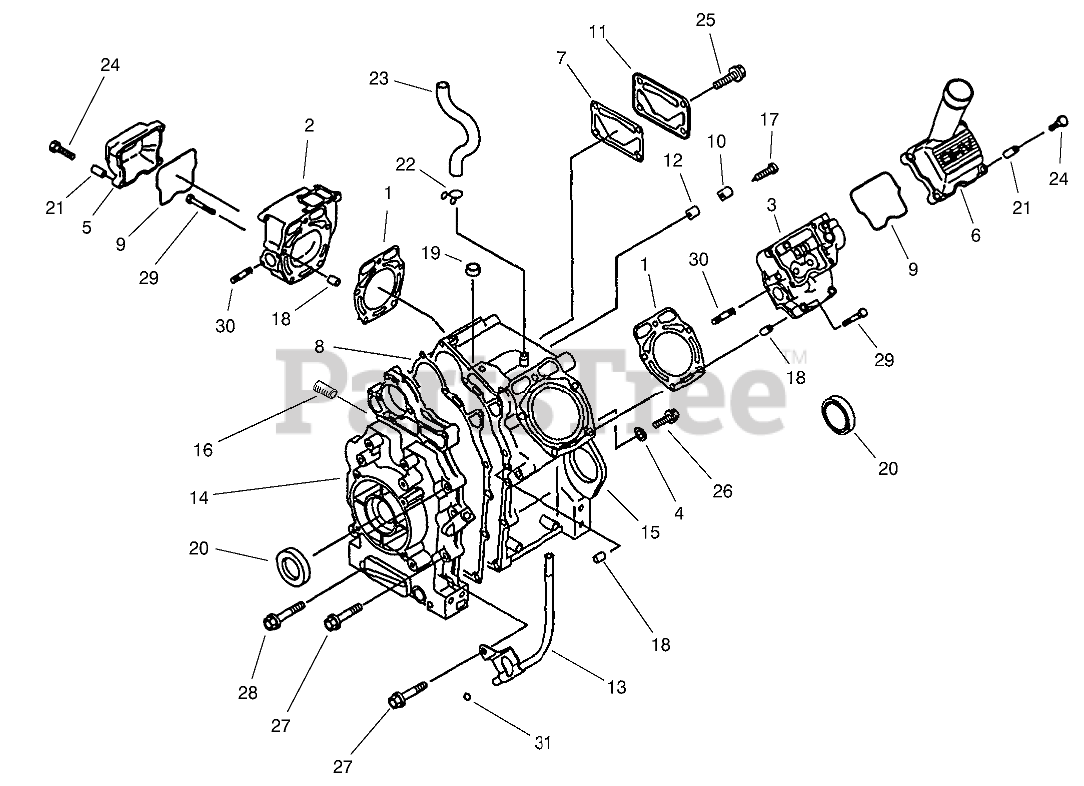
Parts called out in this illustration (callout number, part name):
1	GASKET HEAD
2	HEAD COMP CYL
3	HEAD COMP CYL
4	GASKET
5	CASE-ROCKER
6	CASE-ROCKER
7	GASKET
8	GASKET-CRANKCASE COVER
9	GASKET-ROCKERCASE
10	PLATE
11	COVER
12	VALVE
13	PIPE - OIL LEVEL
14	COVER-CRANKCASE
15	Crankcase-Comp
16	JOINT
17	SCREW
19	SEAL-OIL, VC (6X10X2.5)
20	SEAL-OIL
21	COLLAR
22	CLAMP
24	BOLT-FLANGED (6X25)
25	BOLT-FLANGED
26	BOLT-FLANGED
27	BOLT-FLANGED
28	BOLT-FLANGED
29	BOLT-FLANGED
30	BOLT-STUD
31	O-RING
